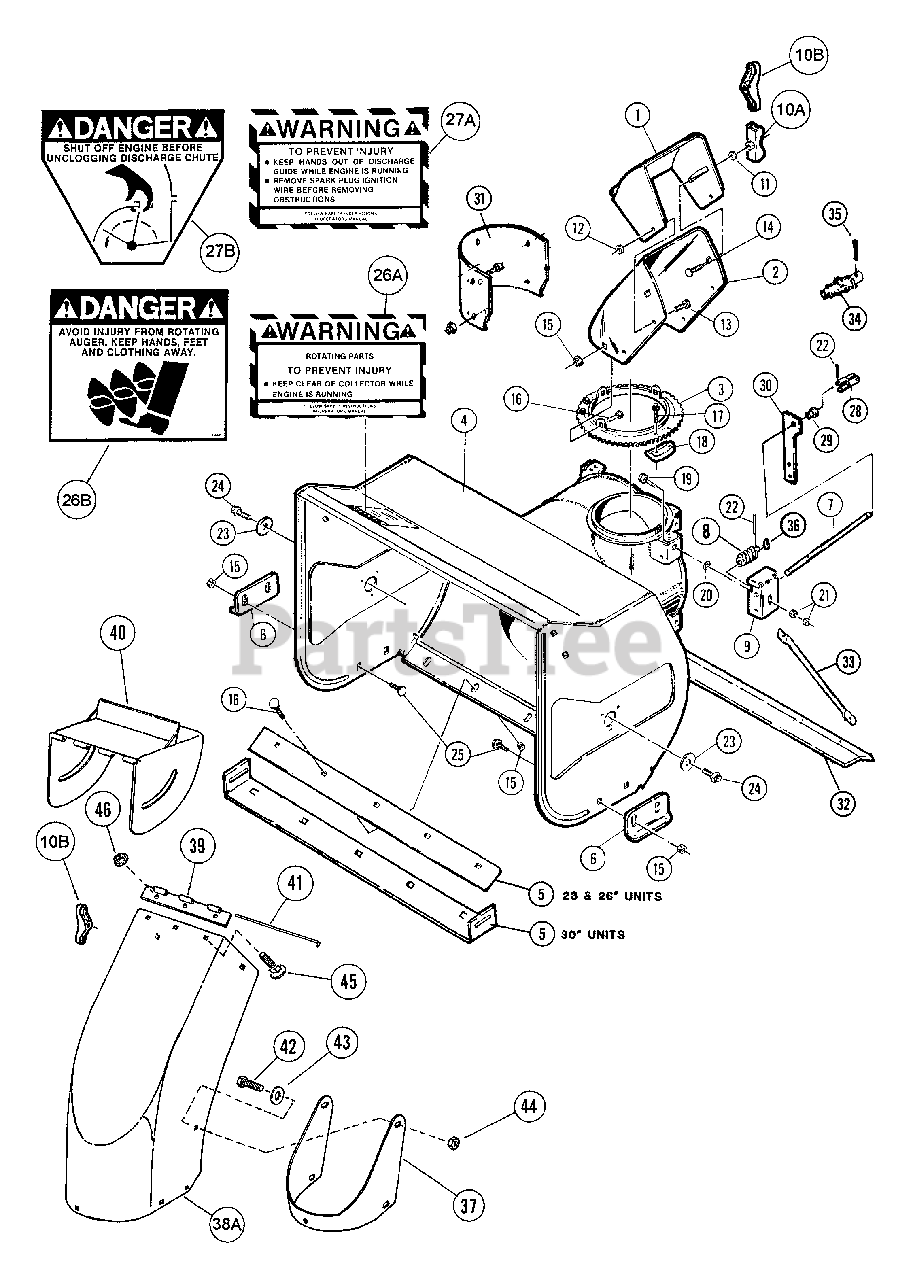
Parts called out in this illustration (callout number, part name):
1	DEFLECTOR, Discharge
2	ASSEMBLY, Discharge Chute
3	RING, Chute
4	HOUSING, 23" Blower
5	BLADE, 23" Scraper
6	SKID-SHOE
7	SHAFT, Worm
8	WORM
9	BRACKET, Worm Shaft
10A	WING-NUT
10B	WING-NUT, 5/16-18
11	WASHER, 1/4 SAE
12	NUT, 5/16-18 Hex Ctr. Lock
13	SCREW, 5/16-18 x 1/2" Hex Head Cap, Grade 2
14	BOLT, 1/4-20 x 3/4" Short Neck Carriage, Grade 5
15	NUT, 5/16-18 Hex Fl. Lock
16	BOLT, 5/16-18 x 5/8" Square Neck Carriage, Grade 5
17	SCREW, #10-24 x 5/8" Hex Head Washer Face
18	RETAINER (Chute Ring to Housing)
19	BOLT, 5/16-18 x 1" Carriage
20	RETAINER, 5/16 Bolt
21	NUT, 5/16-18 Hex, Grade B or 5
22	ROLL-PIN, 1/8 x 3/4"
23	WASHER, 3/8" Flat
24	SCREW, 3/8-16 x 1/2" Hex Self-Tap (Serial 03 Prefix)
25	BOLT, 5/16-18 x 3/4" Short Neck Carriage, Grade 5
26A	DECAL, Collector Warning
26B	DECAL, Collector Danger
27A	DECAL, Deflector Warning
27B	DECAL, Deflector Danger
28	CONNECTOR
29	BUSHING
30	BRK'T, Worm Shaft Support
31	EXTENSION, 30" Discharge Chute
32	BAR, Stiffener - (30" Units only)
33	BRACE, Side - 30" Units only
34	UNIVERSAL-JOINT (30")
35	COTTER-PIN, 1/8 x 1"
36	WASHER, Spring Steel
37	BRACE, Chute
38A	CHUTE (Plastic)
39	HINGE, Chute
40	ASSEMBLY, Chute Deflector
41	PIN, Hinge
42	SCREW, 5/16-24 x 3/4" Hex Head Cap
43	WASHER, 5/16 SAE
44	NUT, 5/16-24 Hex Center Lock
45	BOLT, #10-24 x 1/2" Square Neck Carriage, Grade 2
46	NUT, #10-24 Hex Flange Lock
